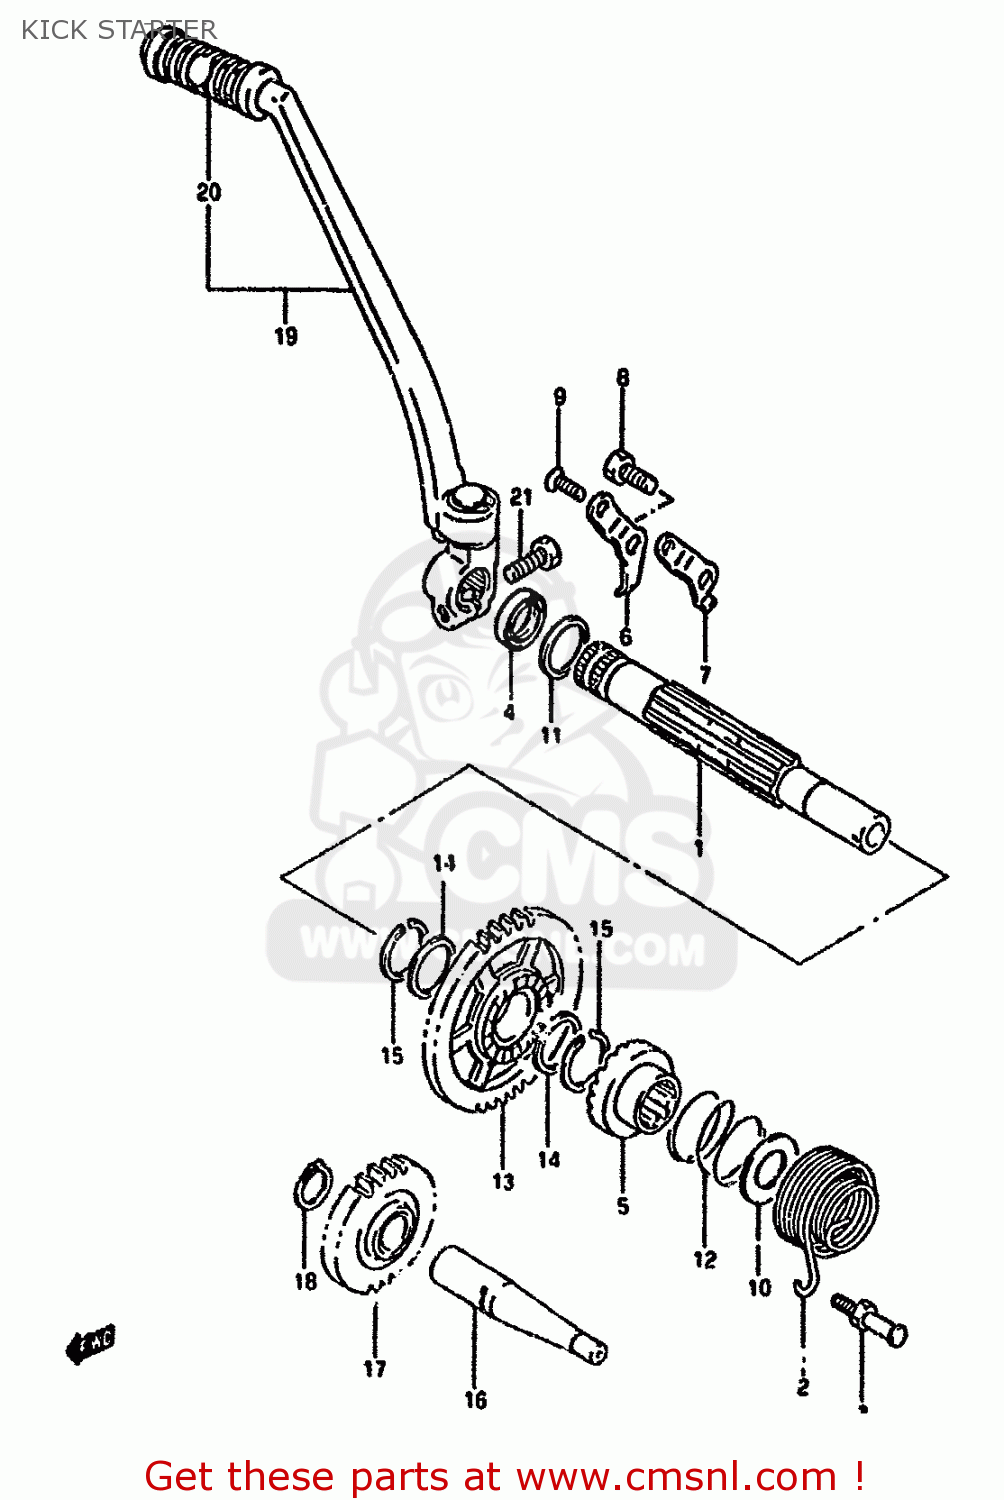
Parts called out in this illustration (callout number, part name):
1	SHAFT,KICK STARTER
2	SPRING
3	BOLT,KICK SHAFT SPRING
4	SEAL,OIL(20X27X6)
5	STARTER,KICK
6	GUIDE,KICK STARTER
7	STOPPER,KICK STARTER
8	BOLT
9	SCREW
10	WASHER
11	WASHER,THRUST
12	SPRING
13	GEAR,KICK STARTER DRIVE
14	SHIM
15	CIRCLIP
16	SHAFT,KICK STARTER IDLE
17	GEAR,KICK STARTER IDLE
18	CIRCLIP
19	LEVER ASSY,KICK STARTER
20	RUBBER,KICK STARTER PEDAL
21	BOLT 8X25
